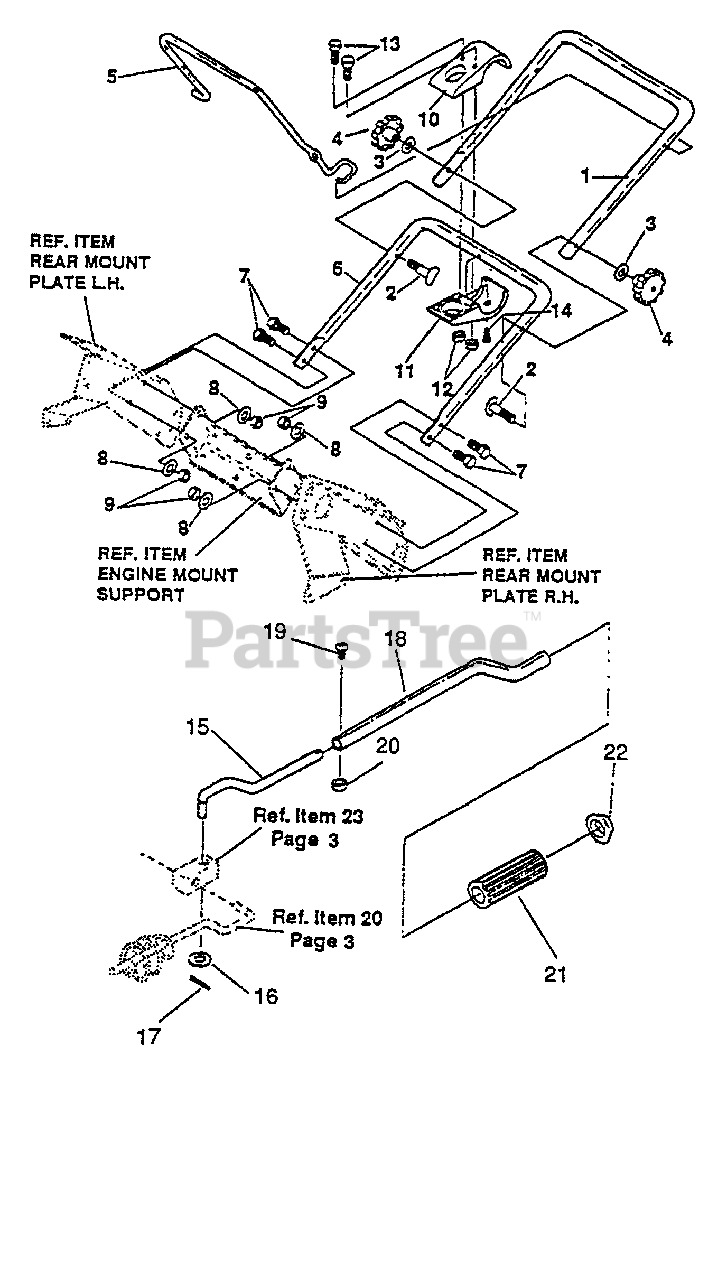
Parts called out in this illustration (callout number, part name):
1	HANDLE, UPPER
2	BOLT 5/16"-18×1-3/4"
3	WASHER
4	KNOB
5	BAR, DRIVE CONTROL LOOP
6	HANDLE, LOWER
7	SCREW 5/16"-18×0.75
8	WASHER
9	NUT, 5/16"-18
10	BRKT HALF, CHUTE CRANK
11	BRKT HALF, CHUTE CRANK
12	NUT
13	SCREW #10-24×1.00
14	SCREW 1/4"-20×0.63
15	ROD, CHUTE CONTROL MIDDLE
16	WASHER, FLAT 0.390×0.75×0.031
17	PIN - COTTER
18	ROD, UPPER CHUTE CONTROL
19	SCREW 010-32×0.88
20	NUT
22	CAP NUT, PUSH-ON
